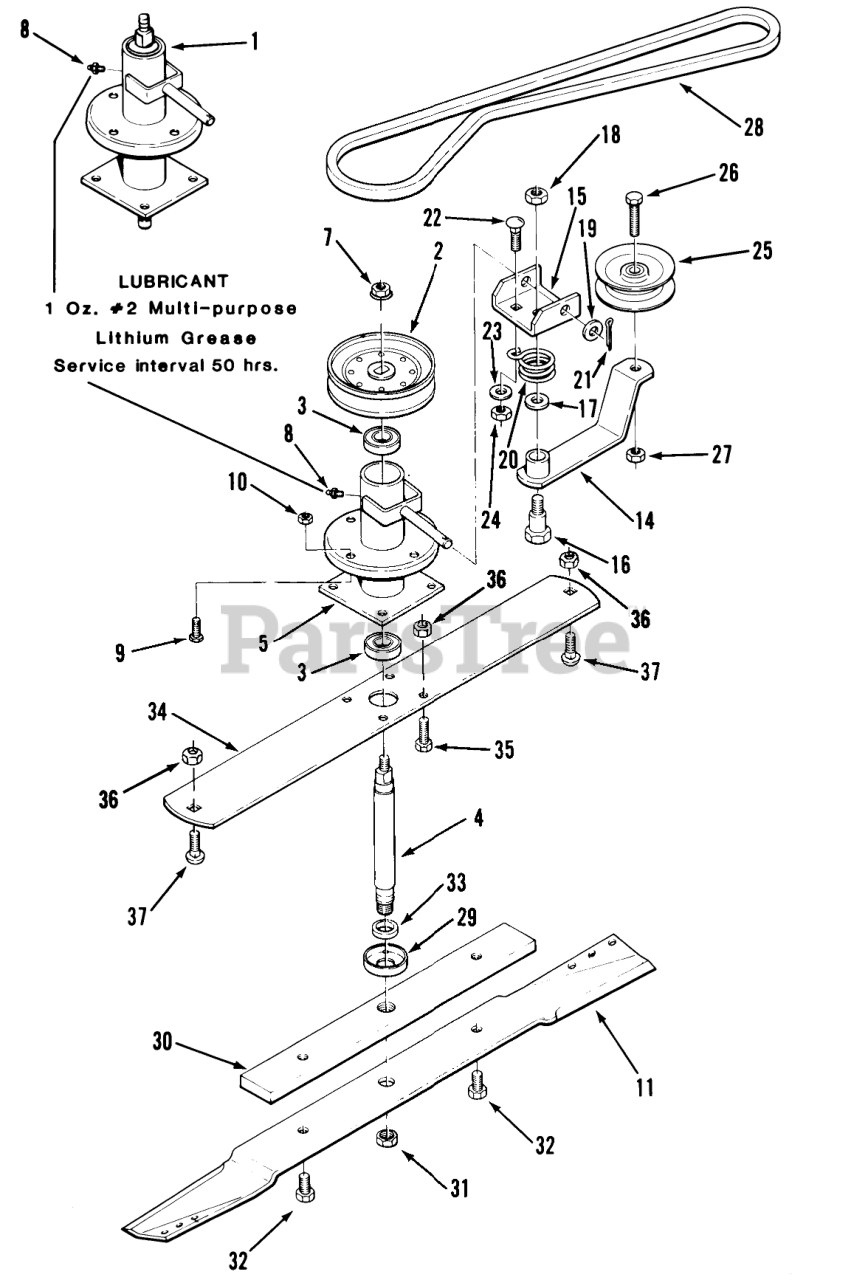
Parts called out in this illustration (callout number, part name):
1	Spindle Assy Complete
2	PULLEY SPINDLE
3	BALL BEARING
4	SHAFT SPINDLE
5	Spindle Housing
6	Washer
7	NUT 3/8-24 WHIZLOCK
8	Zerk
9	Bolt
10	Nut
11	Blade
14	ASSY LEVER R
15	CHANNEL PIVOT R
16	BOLT-SHOULDER
17	WASHER
18	NUT-JAM(7/16-14)
19	Washer
20	SPRING-TORSION
21	Cotter Pin
22	Bolt
23	Washer
24	NUT
25	PULLEY IDLER R
26	Bolt
27	NUT
28	Mower Drive Belt
29	CUP SPINDLE
30	BAR BLADE R
31	Nut
32	HEX BOLT 1/2-13X3/4
33	SPACER-BLADE
34	PLATE SUPPORT R
35	BOLT
36	NUT
37	Bolt
